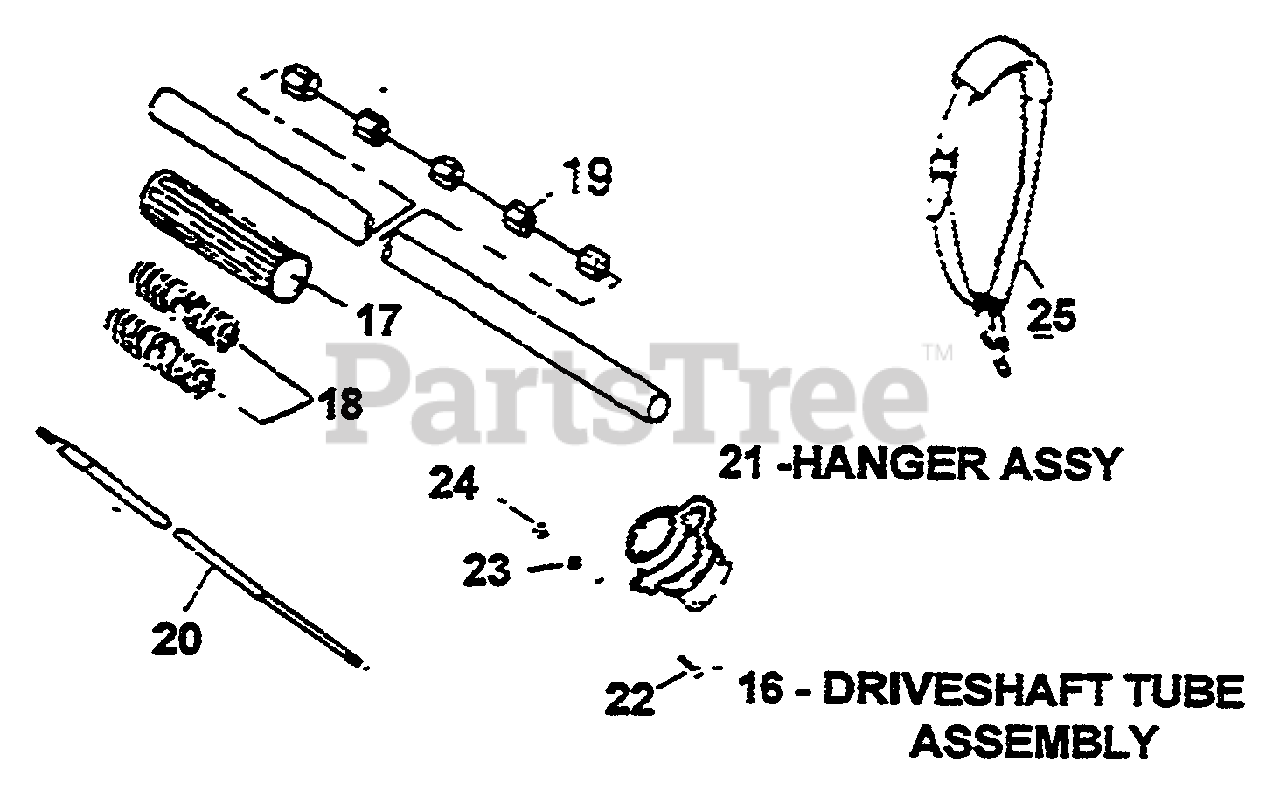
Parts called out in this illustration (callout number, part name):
16	DRIVESHAFT TUBE ASSY
17	GRIP--ANTI-VIBE
18	SPRING--ANTI-VIBE
20	DRIVESHAFT
21	HANGER ASSY
25	HARNESS
